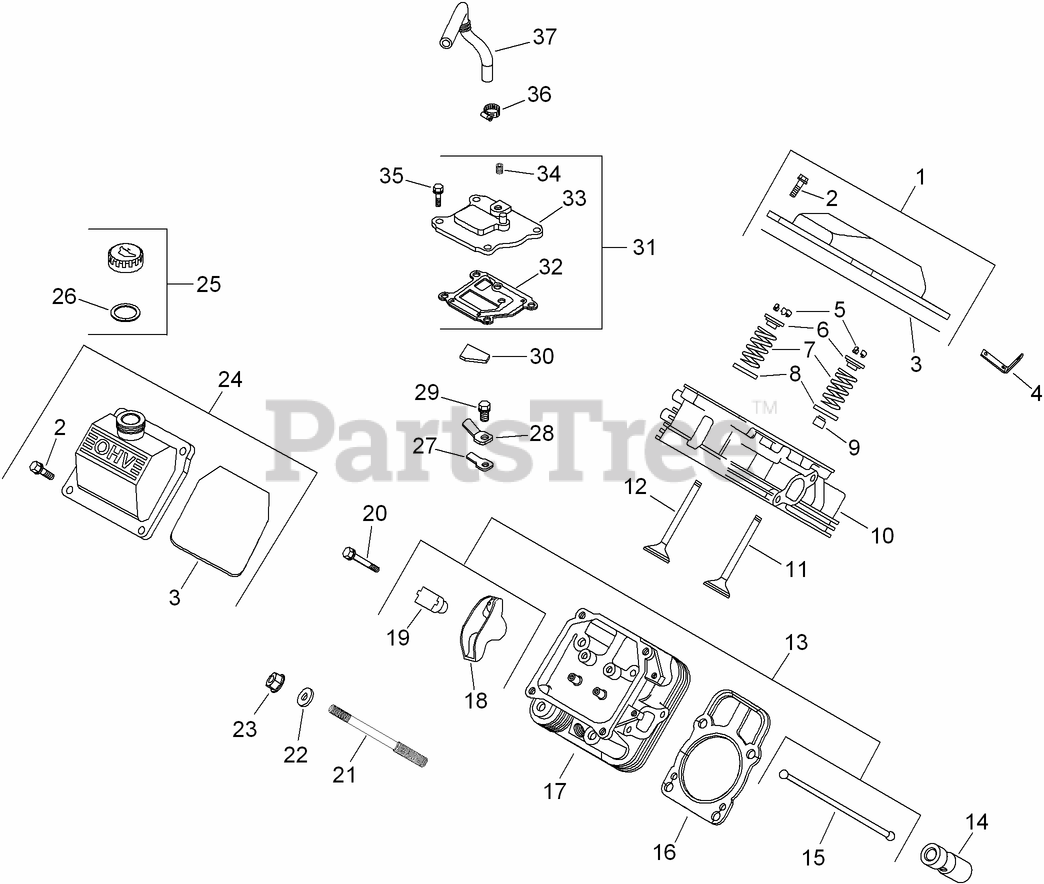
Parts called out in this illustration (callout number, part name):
1	PLAIN ROCKER COVER KIT (INCLUDES 2, 3)
2	SCREW-FLANGE (M6X1.0X30)
3	O-RING
4	STRAP-LIFTING
5	RETAINER KIT
6	CAP-SPRING, VALVE
7	SPRING-VALVE
8	RETAINER-SPRING
9	SEAL-STEM, VALVE
10	CYLINDER HEAD No.1 ASM (INCLUDES 25 072 04-S)
11	VALVE-INTAKE (STD)
11	VALVE-INTAKE (.25)
12	VALVE-EXHAUST (STD)
12	VALVE-EXHAUST (.25)
13	VALVE TRAIN KIT (INCLUDES 15,18 and 19)
14	HYDRAULIC VALVE LIFTER KIT (INCLUDES 25 357 14-S)
15	ROD-PUSH
16	CYLINDER HEAD GASKET KIT
17	CYLINDER HEAD No.2 ASM (INCLUDES 25 072 04-S)
18	ARM-ROCKER
19	PIVOT-ARM, ROCKER
20	SCREW-FLANGE (M6X1.0X34)
21	STUD (M8X1.25xM10X1.5x105MM)
22	WASHER-FLAT (8.6 MM)
23	NUT-FLANGE (M8X1.25)
24	OIL FILL ROCKER COVER KIT (INCLUDES 2, 3)
25	OIL FILL CAP KIT (YELLOW) (INCLUDES 26)
26	O-RING (DIPSTICK)
27	REED-BREATHER
28	RETAINER-REED
29	SCREW-HHFTF (M5X.80X10)
30	FILTER-BREATHER
31	BREATHER ASM (INCLUDES 32, 33)
32	GASKET-BREATHER
33	COVER-BREATHER
34	PLUG-PIPE, COUNTERSUNK (1/8)
35	SCREW-HHFTF (M6X1.0X20)
36	CLAMP-HOSE, SPRING (1/2)
37	HOSE-BREATHER
